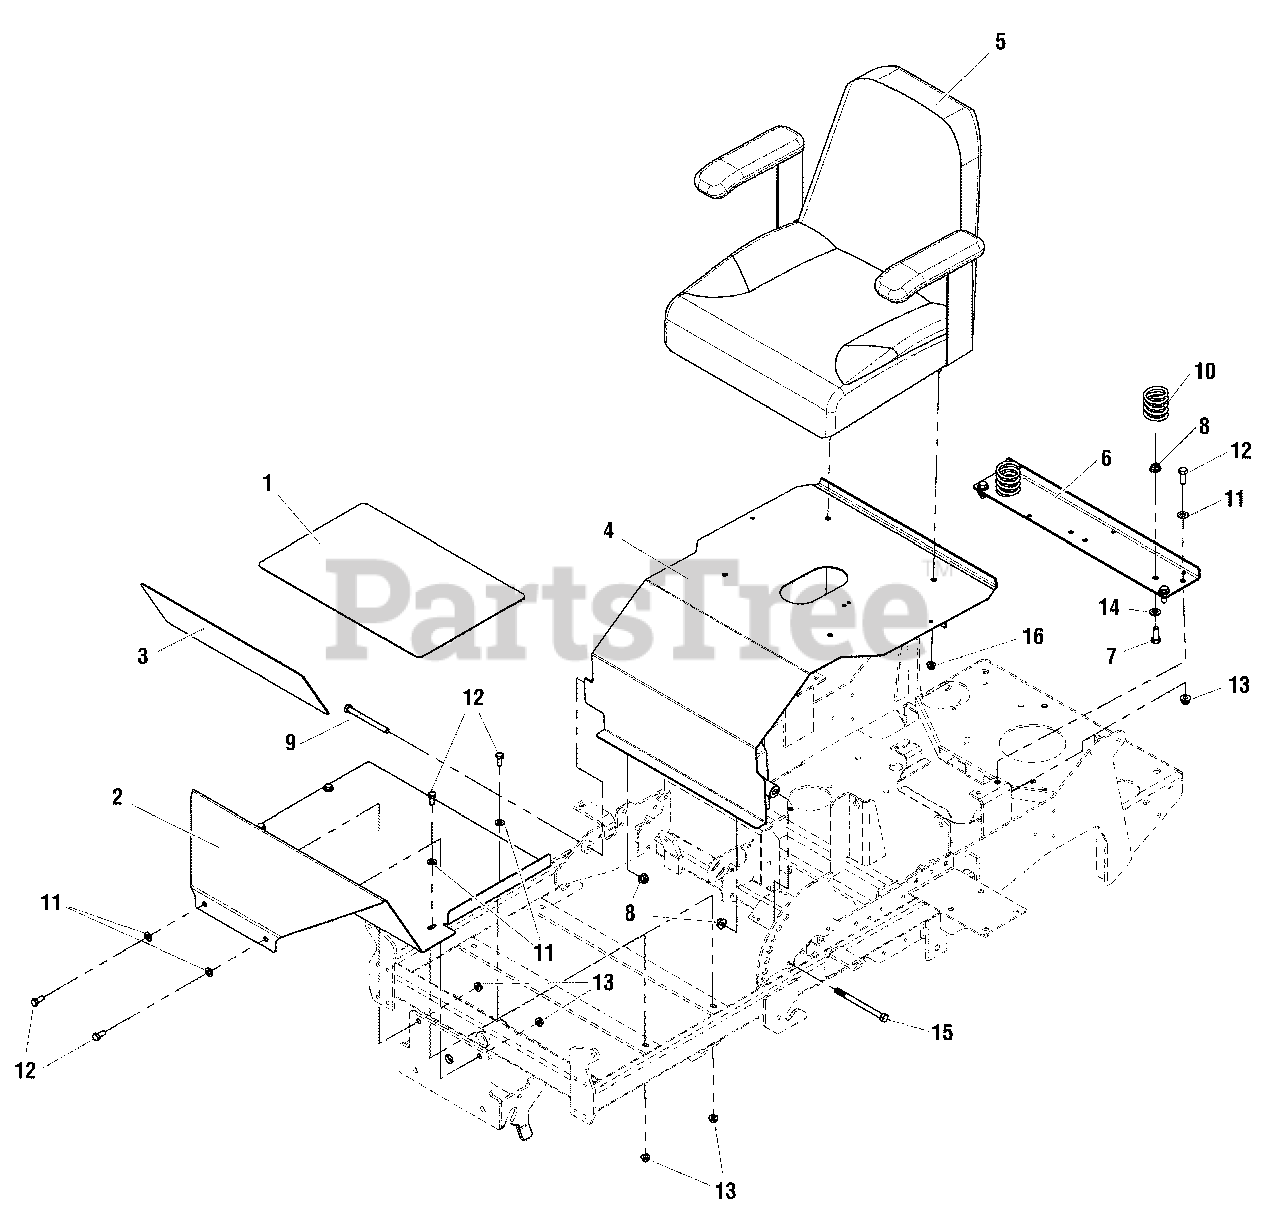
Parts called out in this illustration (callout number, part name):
1	SAFETY WALK, 11.50 X 17.38
2	PLATE, FLOOR DETAIL
3	SAFETY WALK, 17.38 X 6.00
4	WELD, SEAT PLATE - ORG
5	SEAT, XB-180, NO LOGO, BLACK
6	MOUNT, OIL FILTER - ORG
7	BOLT, 3/8-16 X 1" GD5 YZ
8	NUT, 3/8-16 HEX NYLOCK FLANGE
9	BOLT, 3/8-16 X 4" GD5 YZ
10	SPRING, SEAT SUPPORT
11	WASHER, 5/16" GD.9 FLAT
12	BOLT, 5/16-18 X 1" GD5 YZ
13	NUT, 5/16-18 HEX NYLOCK FLANGE
14	WASHER, 3/8" SAE
15	BOLT, 3/8-16 X 5" GD5 YZ
16	NUT, 5/16-18 HEX NYLON LOCK
17	SPRING, EXTENSION, SEAT ADJUSTMENT (BLK OR SLVR)
